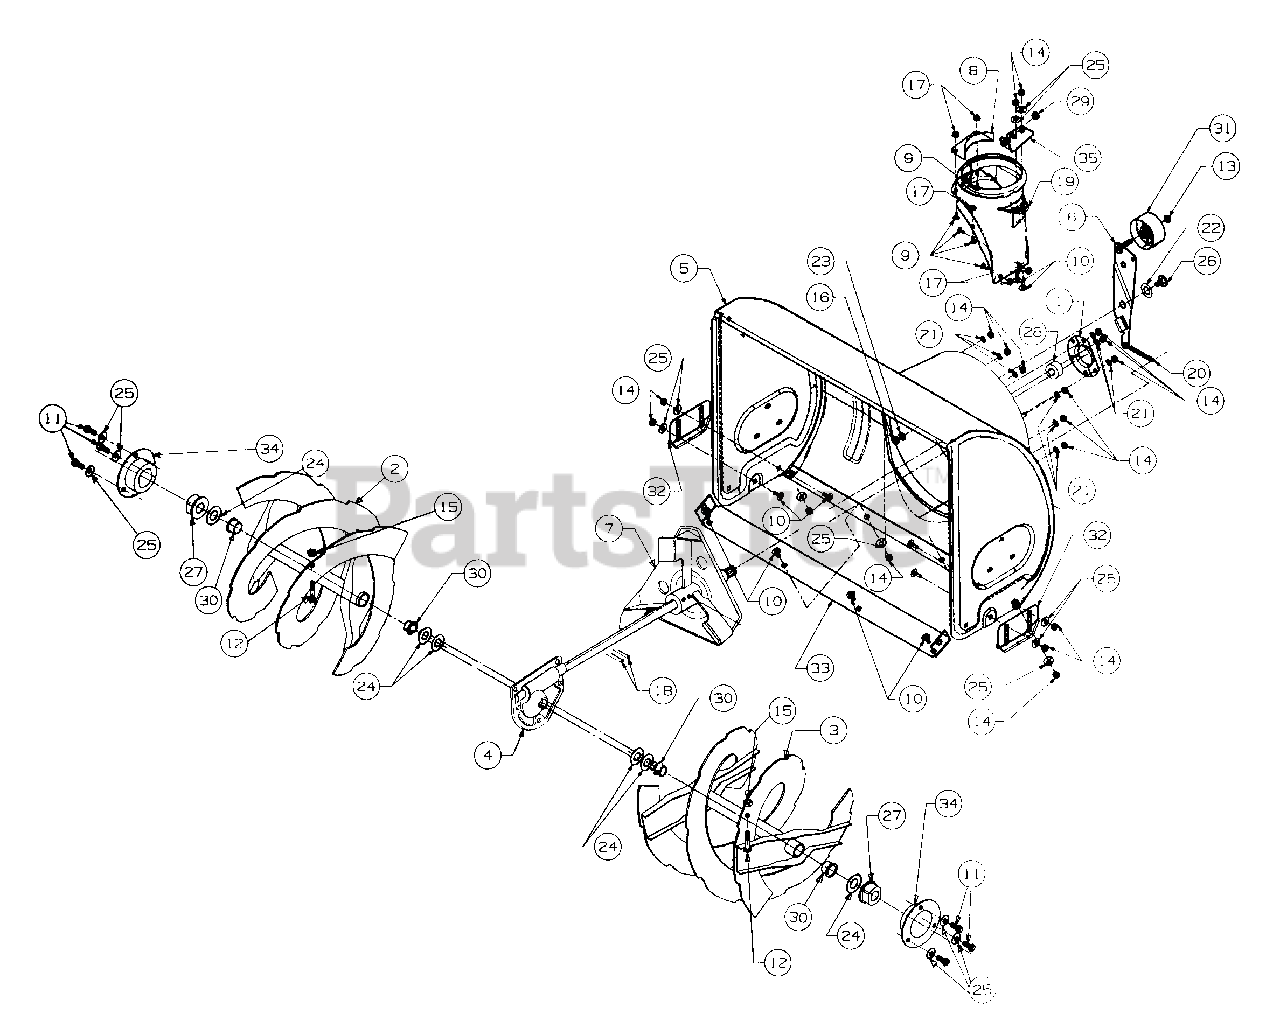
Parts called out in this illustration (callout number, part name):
1	Housing-Bearing
2	Spiral Assembly - R.H. 24"
2	Spiral Assembly - R.H. 26"
3	Spiral Assembly - L.H. 24"
3	Spiral Assembly - L.H. 26"
4	Gear Assembly 24"
4	Gear Assembly 26"
5	Housing Assembly 24"
7	Impeller Assembly
8	Reinforcement-Chute
9	Screw-Carriage
10	Screw-Carriage
11	Screw-Hex
12	Shear Bolt
13	Nut-Hex Lock
14	Nut-Hex
15	Nut-Hex
16	Nut-Hex
17	Nut-Hex Lock
18	Pin-Spring
19	Adapter-Chute
20	Spring
21	Washer-Lock
22	Washer-Flat
23	Washer-Lock
24	Washer-Flat
25	Washer-Bell
26	Screw-Shoulder
27	Bearing Flange
28	Bearing Ball
29	Bushing-Plastic
30	Bushing-Flange
31	Idler-Flat
32	Shoe-Slide
33	Shave Plate 24"
33	Shave Plate 26"
34	Housing-Bearing
35	Bracket-Chute Crank
